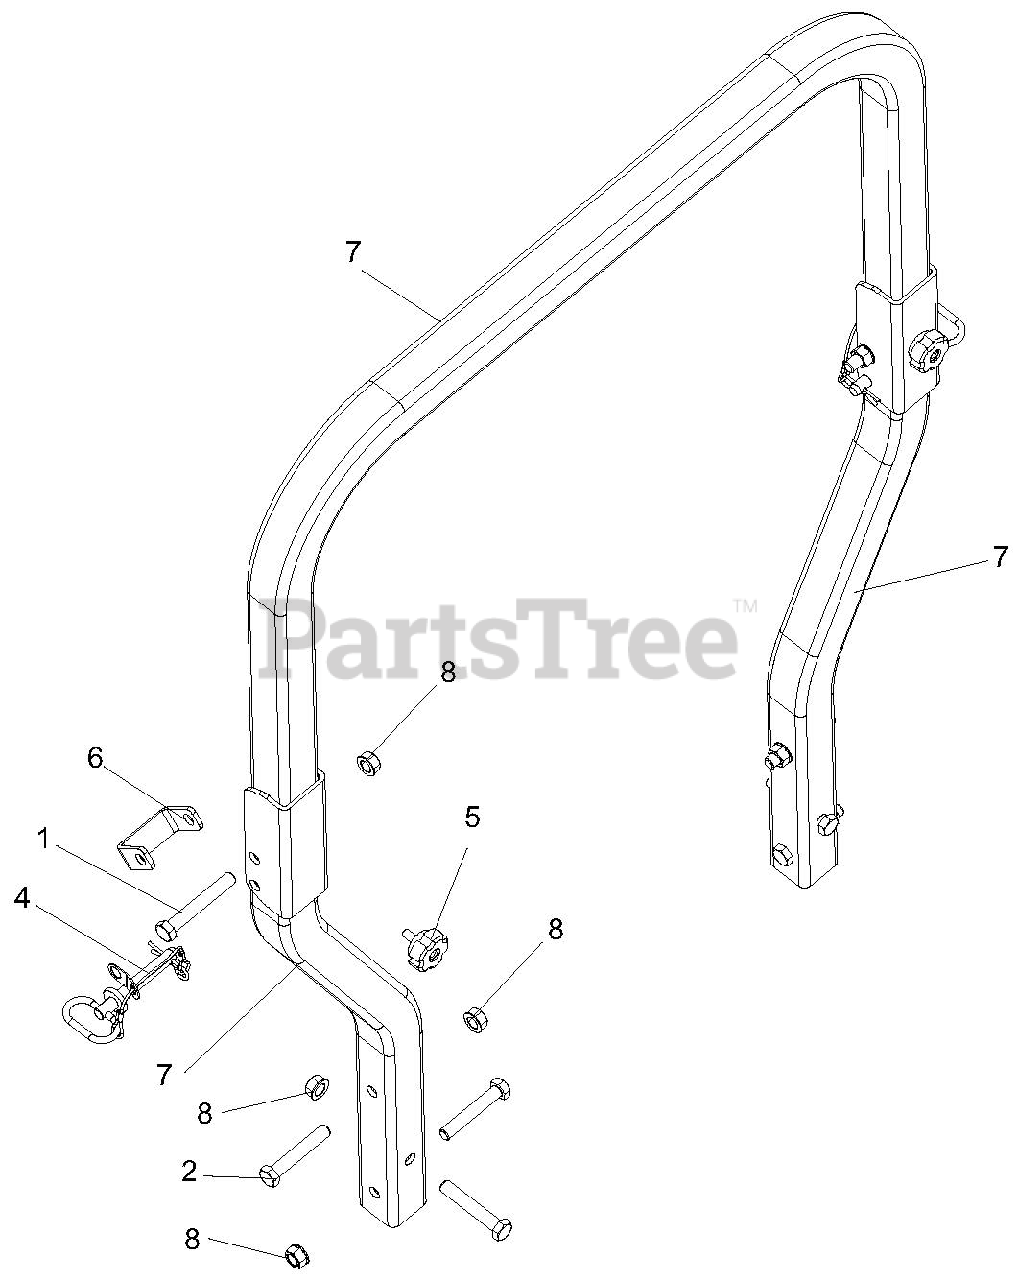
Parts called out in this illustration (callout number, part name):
1	BLT-HEX .50-13X3.50 GR5 YWZC
2	BLT-HEX .50-13X3.00 GR5 YWZC
4	ASSY, ROPS PIN/LANYARD
5	KNOB, ROUND 5/16-18 X .750
6	BRKT, ROPS STOP
7	ROPS, PRO-TURN 400 REPLACEMENT
8	NUT, LK-TOP-FLG .50-13 YWZC
